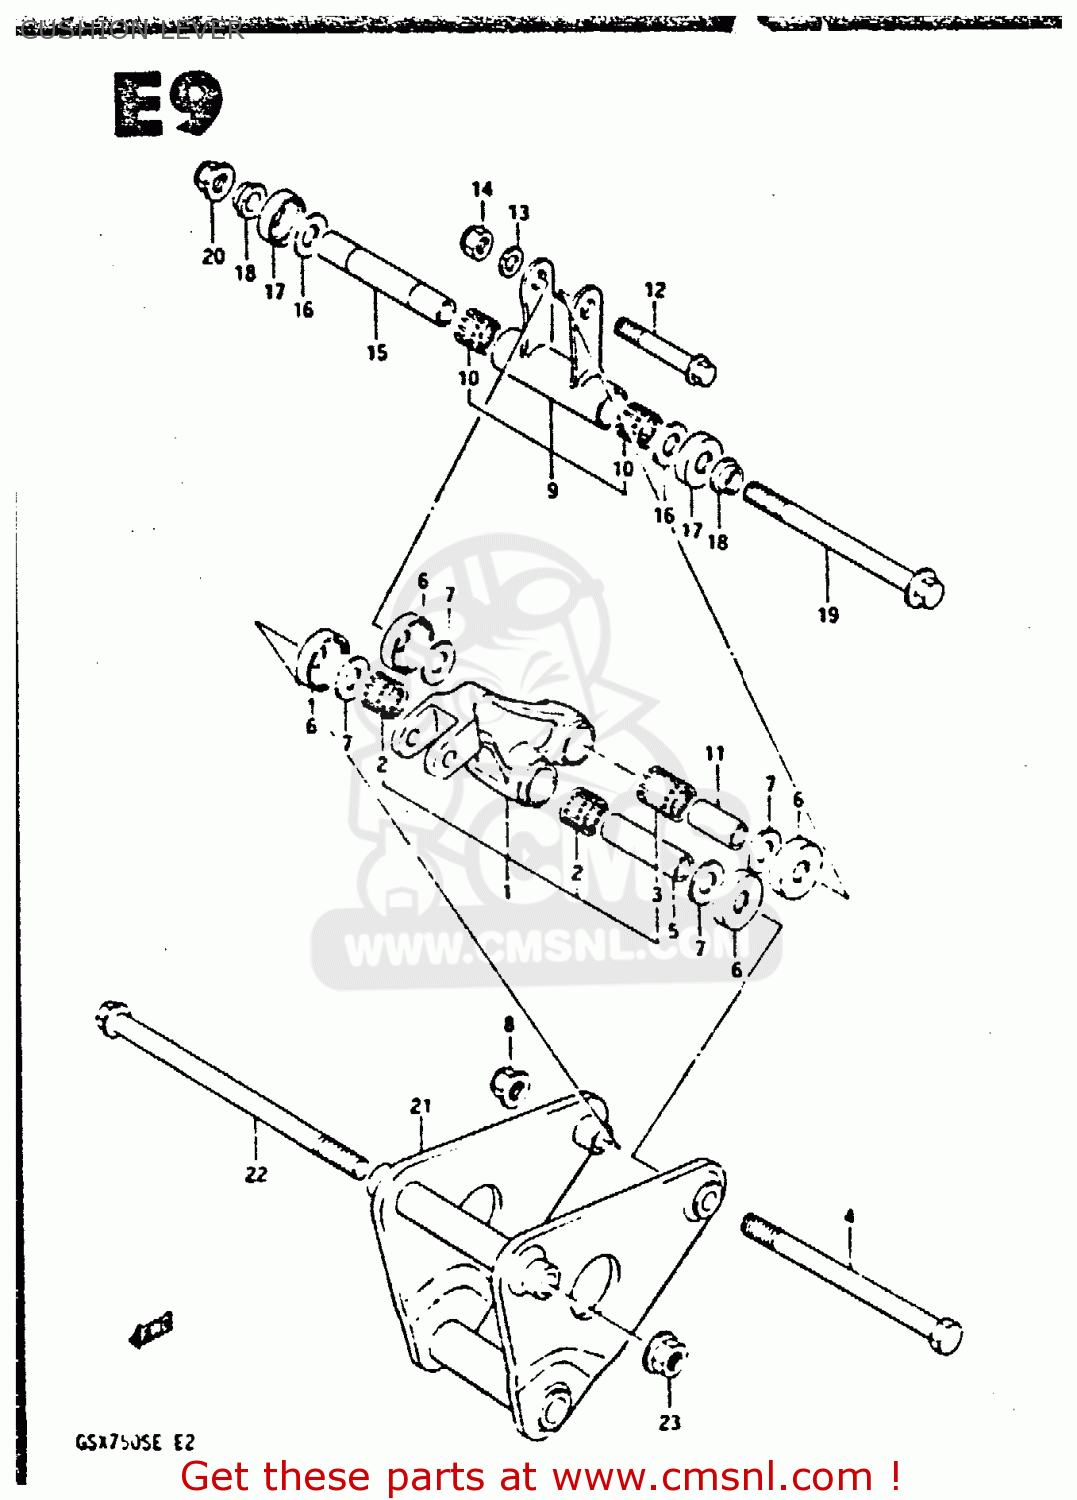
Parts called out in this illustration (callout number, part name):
1	LEVER SET,REAR CUSHION
2	ROLLER BEARING (17X24X2
3	ROLLER BEARING (17X24X25)
4	SHAFT,RR CUSHION LEVER
5	SPACER,REAR CUSHION LEVER
6	COVER,RR SWGARM DUST SEAL
7	WASHER
8	NUT 12MM
9	ROD SET,REAR CUSHION
10	ROLLER BEARING (17X24X2
11	SPACER,RR CUSHION LEVER ROD UP
12	BOLT, UPPER
13	WASHER
14	NUT
15	SPACER,RR CUSHION LVR ROD LOW
16	WASHER
17	COVER,RR SWGARM DUST SEAL
18	SPACER,REAR CUSHION ROD
19	BOLT,CUSHION ROD
20	NUT 12MM
21	BRACKET,REAR SHOCK ABSORBER
22	SHAFT,SHOCK ABSORBER BRACKET
23	NUT
